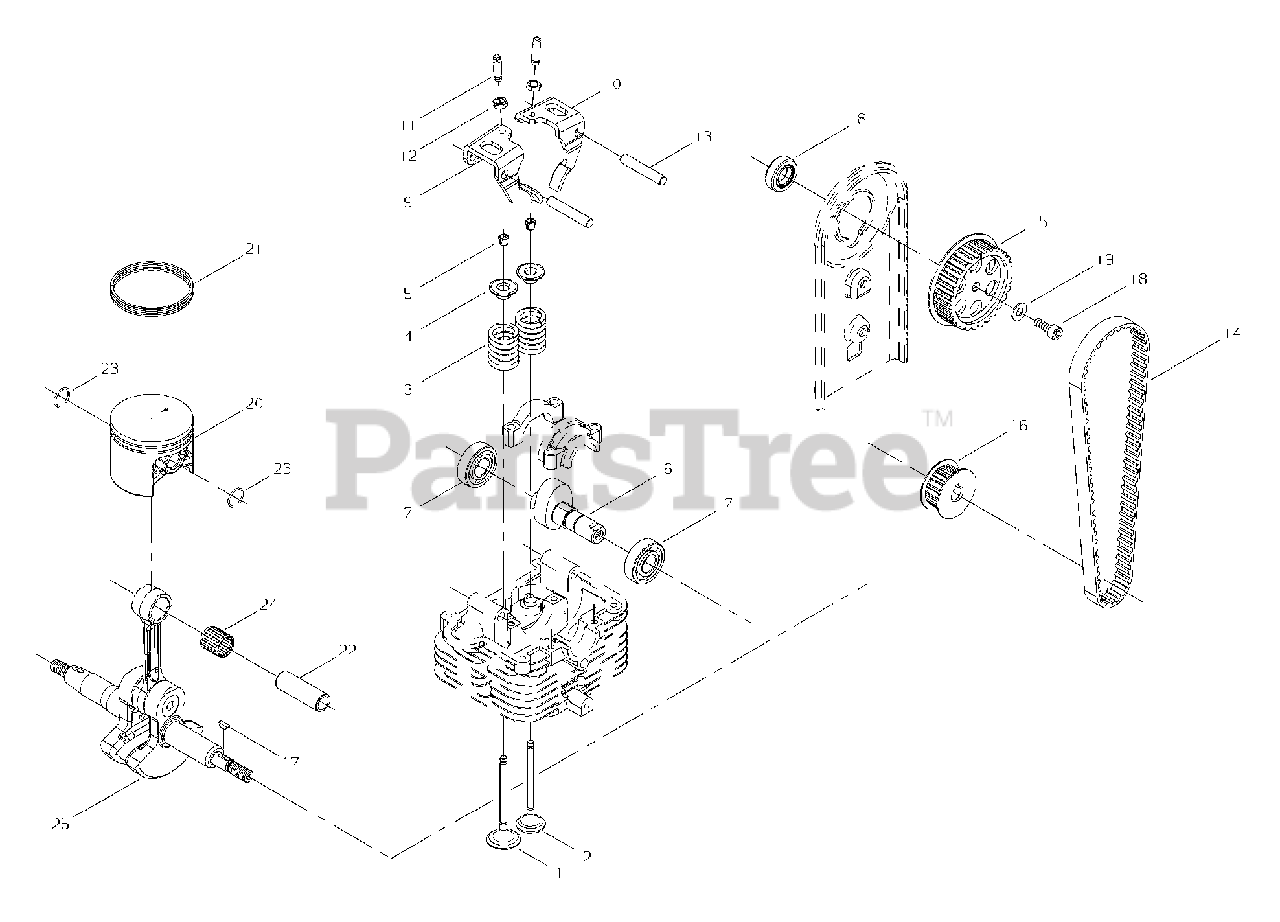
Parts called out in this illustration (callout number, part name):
1	VALVE, INTAKE
2	EXHAUST
3	SPRING, VALVE
4	RETAINER
5	VALVE KEEPER
6	CAMSHAFT
7	BEARING, BALL - 6001
8	SEAL, OIL - 12
9	ARM, ROCKER
10	ARM, ROCKER
11	SCREW, ADJUST
12	LOCKNUT, ADJUSTER
13	ROLLER
14	BELT
15	PULLEY, CAM
16	CRANK PULLEY
17	KEY - 3X10
18	SCREW - 5X14
19	WASHER - 5
20	PISTON
21	RING, PISTON
22	PIN, PISTON
23	RING, RETAINING
24	BEARING, NEEDLE
25	CRANKSHAFT ASSY
